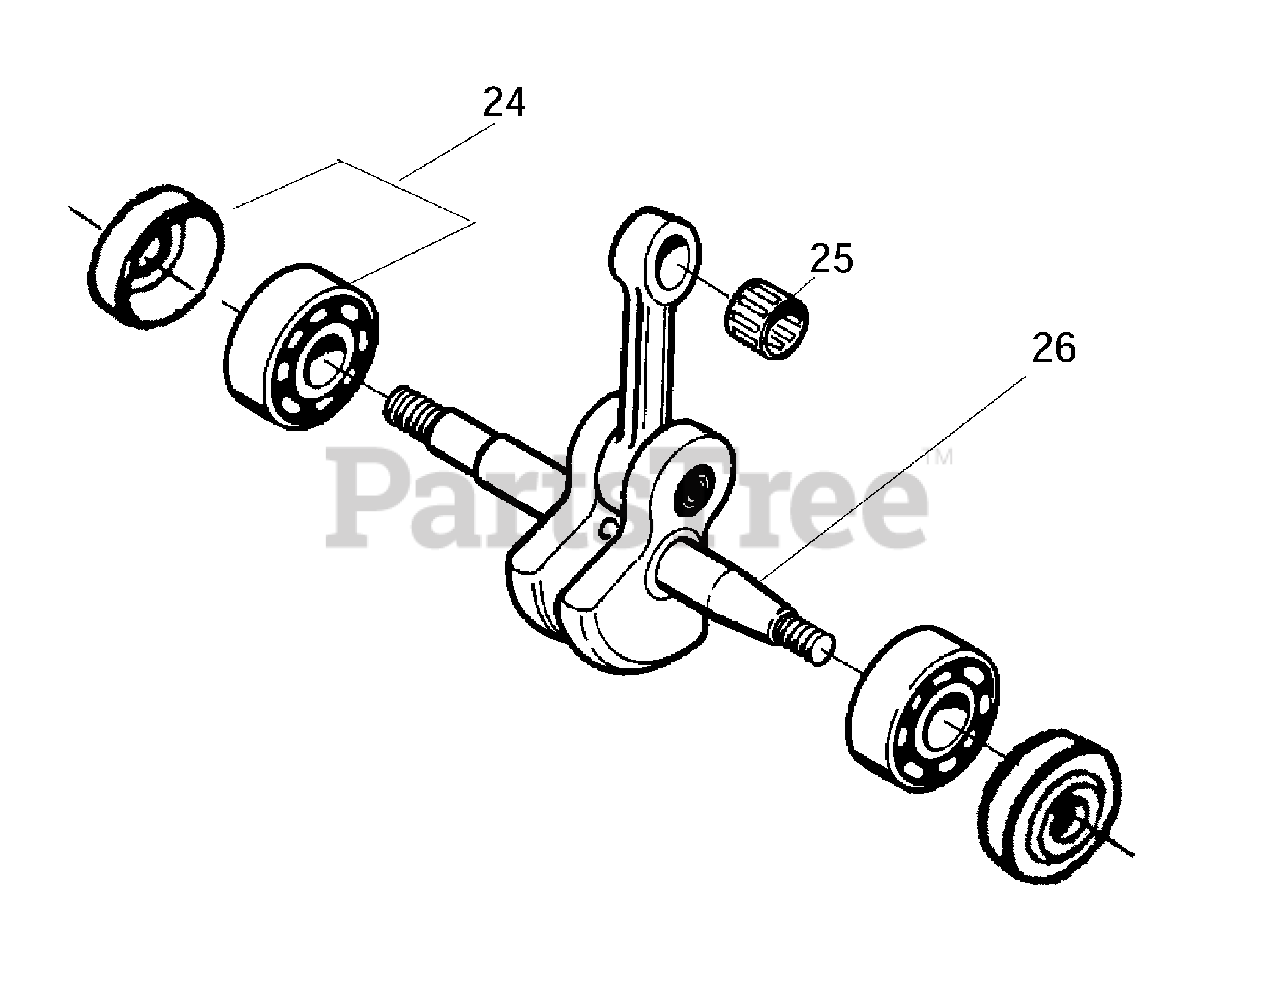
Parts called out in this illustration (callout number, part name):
24	Assy. -Bearing and Seal
25	Piston Pin Bearing
26	Crankshaft & Rod Assembly
